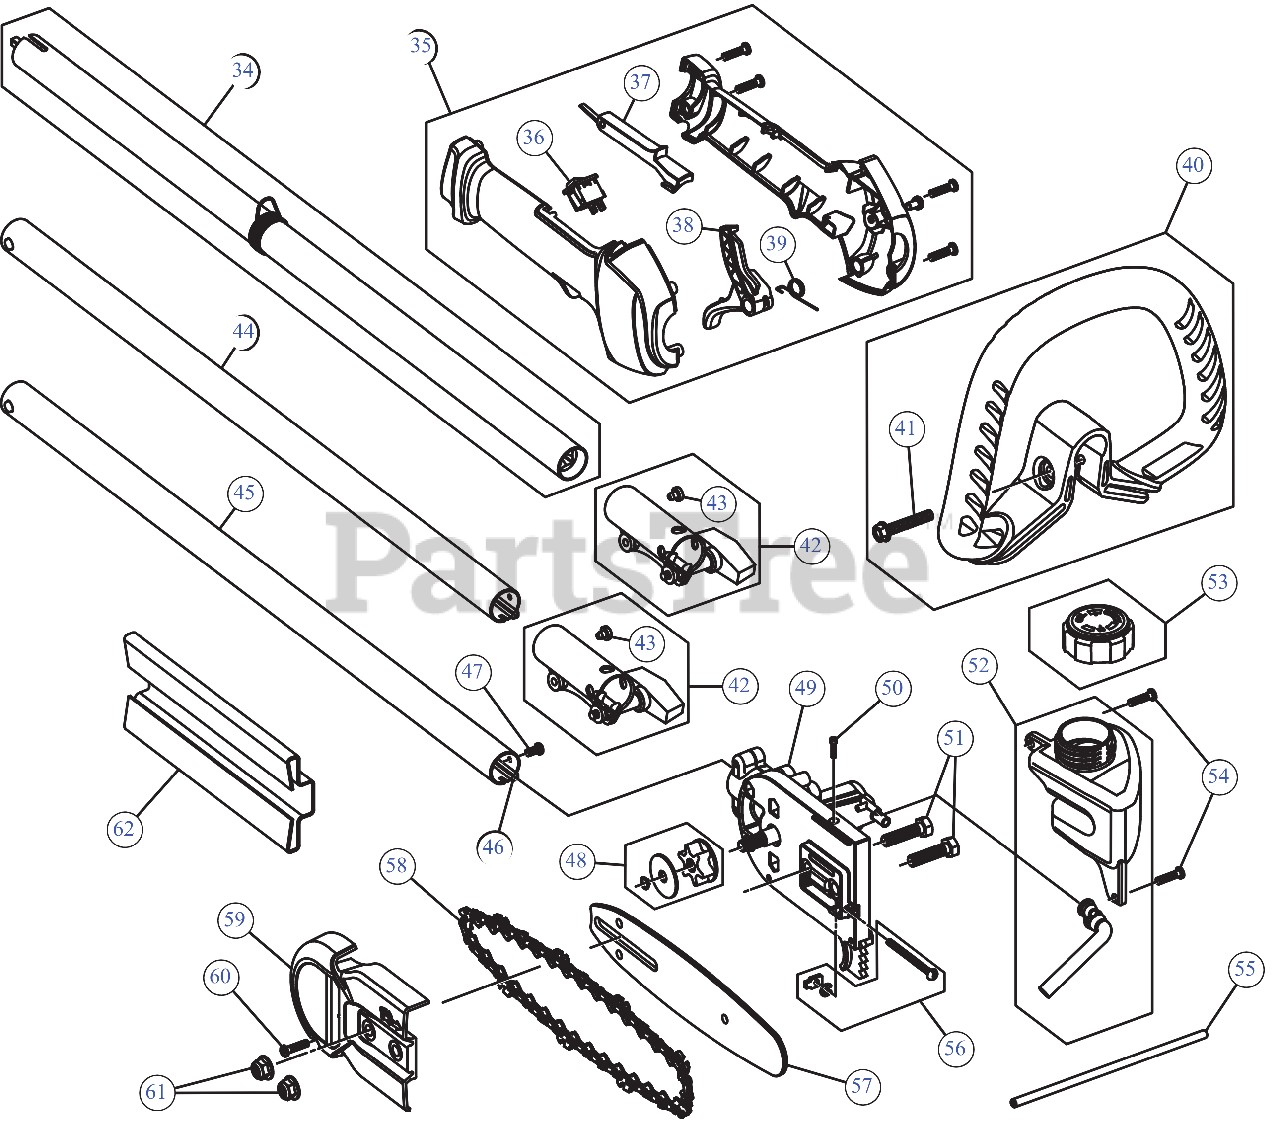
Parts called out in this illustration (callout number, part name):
34	BOOM ASSEMBLY UPR
35	THROTTLE GRIP ASSEMBLY
36	SW, MOMENTARY ON/O
37	LEVER LOCK OUT
38	THROTTLE TRIGGER
39	SPRING TRIG
40	HANDLE ASSEMBLY
41	BOLT 1/4-20X1 1/2
42	COUPLER ASSEMBLY
43	SCREW, 10-32X.250 TA
44	EXTENSION BOOM ASSEMBLY
45	BOOM ASSEMBLY 24"
46	LOWERIBLE DRIVE SHAFT
47	SCREW 1/4-20 X.500
48	SPROCKET ASSEMBLY
49	GEAR BOX ASSEMBLY
50	SCREW 4X40X.50
51	SCREW 5/16-18 x 1.25 GR5
52	OIL TANK ASSEMBLY
53	FUEL CAP ASSEMBLY
54	SCREW, #8-16X.750 PH
55	OIL LINE
56	CHAIN TENSION HDW
57	BAR 10"
58	CHAIN 10"
59	CHAIN GUARD
60	SCREW, #8-16X.750 PH
61	FLANGE LOCK NUT 5/16-18
62	CHAIN COVER
